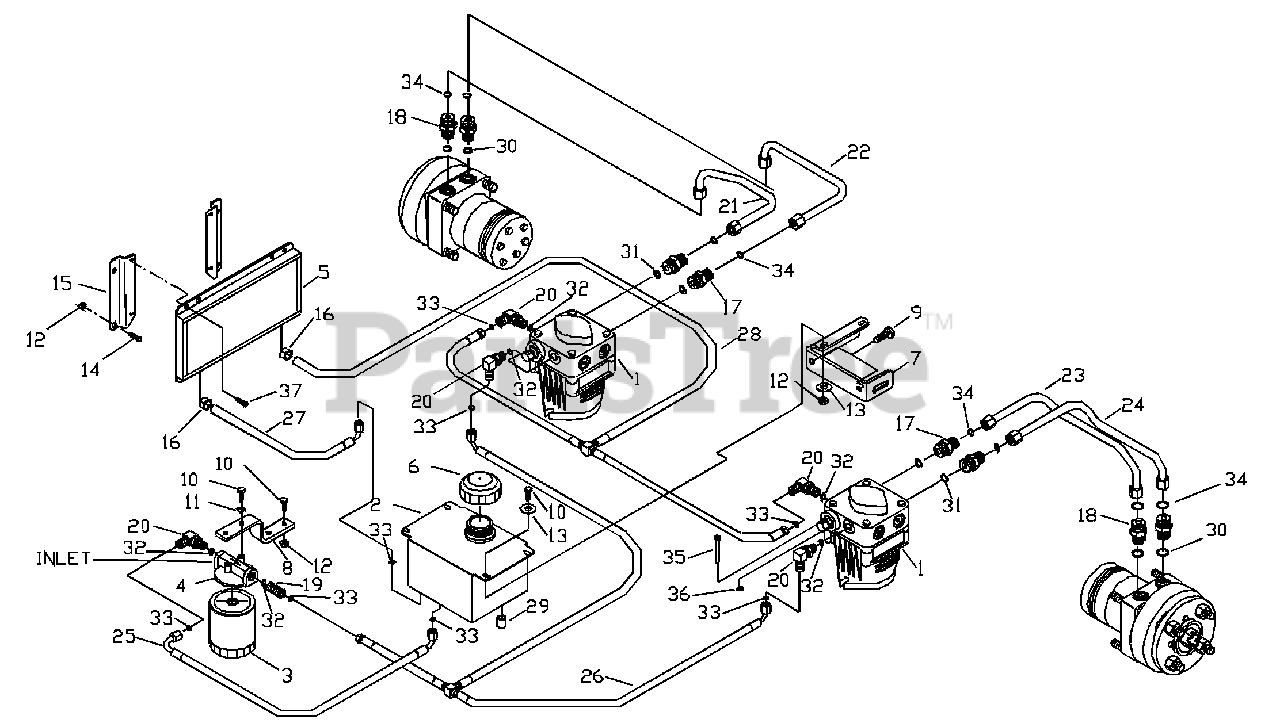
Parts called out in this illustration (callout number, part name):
1	PUMP
4	FILTER HEAD
7	TANK MOUNT LT.
7	TANK MOUNT RT.
8	FILTER BRACKET
9	HCS 5/16 X 3/4
10	HCS 1/4C X 3/4
11	1/4 LOCK WASHER
12	1/4 LOCK NUT
13	1/4 FLAT WASHER
14	HCS 1/4C X 2.0
15	COOLER BRACKET
16	HOSE CLAMP
18	STR. FITTING
30	3/4 "O" RING
31	1/2 "O" RING
32	3/8 "O" RING
33	3/8 "O" RING FLARE
34	3/8 "O" RING FLARE
35	CLEVIS PIN
37	HCS 1/4 SELF TAP
